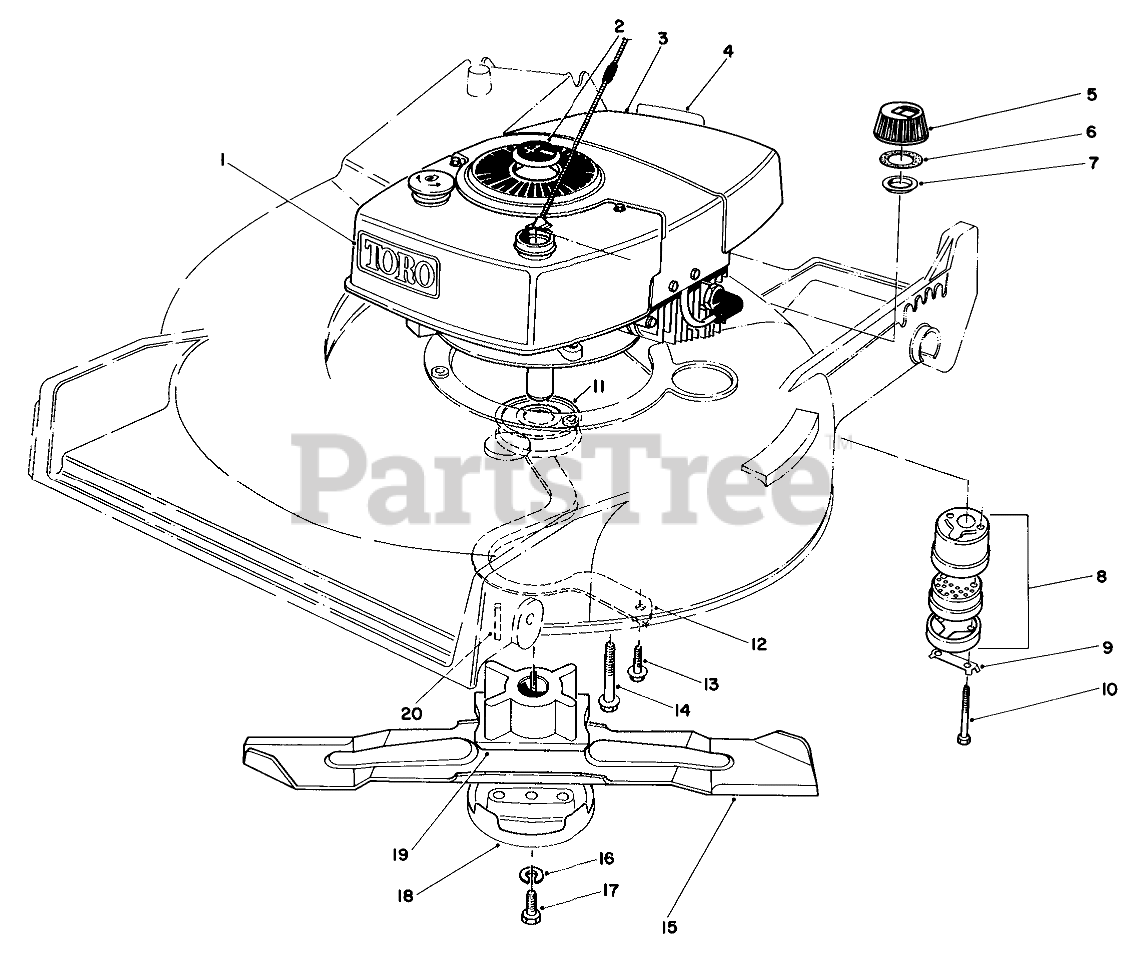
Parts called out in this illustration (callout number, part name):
1	Decal Tow
2	PLUG BUTTON
3	Engine
4	Decal-Maintenan
5	Gas Cap (Incl. Ref. #6 & 7)
6	GASKET
7	GAS CAP BAFFLE
8	Muffler (Incl. Ref. #9 & 10)
9	CLIP - LOCKING
10	SCREW-HH
11	Pulley
12	BELT GUIDE
13	Screw
14	3/8-16 X 2 CAPSCREW
15	BLADE-21in
16	WASHER-LOCK
17	SCREW-BLADE
18	Anti Scalp Cup
19	BLADE RETAINER(DEEP)
20	KEY-SQUARE
